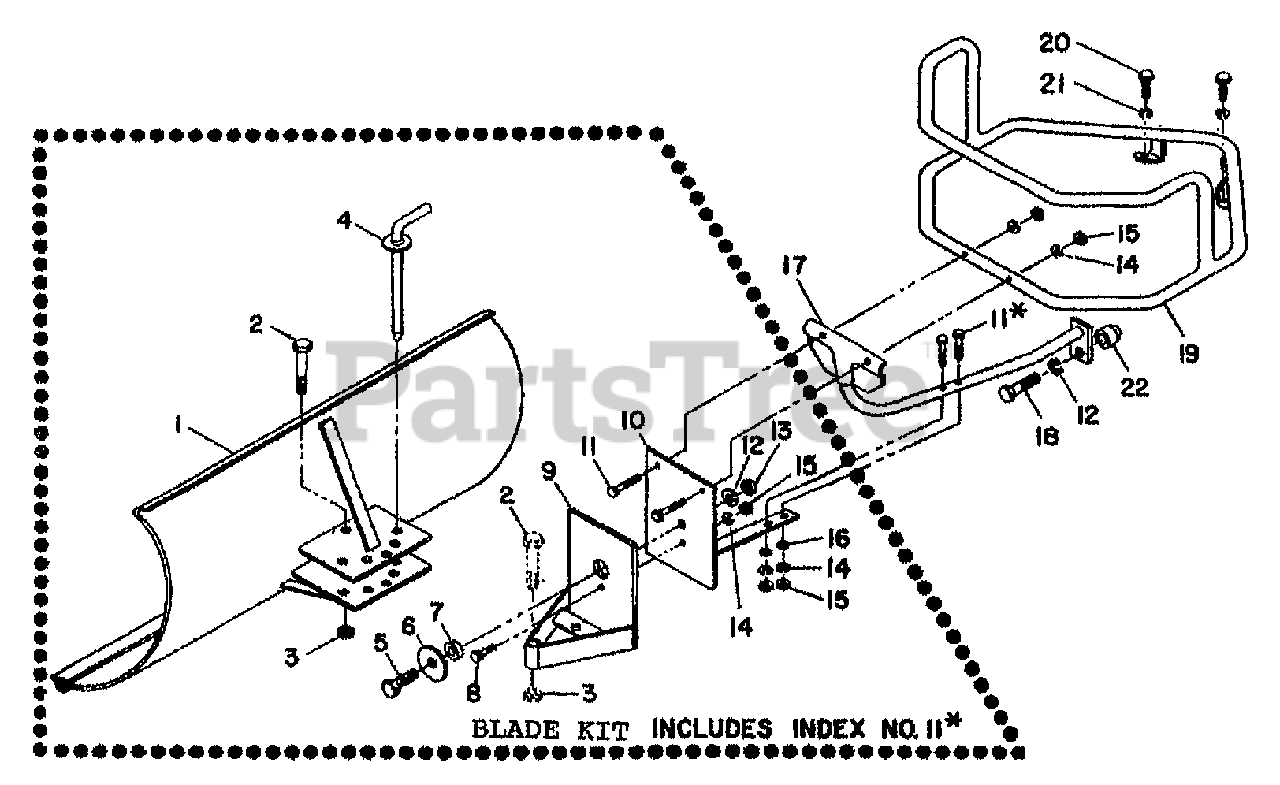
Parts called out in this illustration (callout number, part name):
1	BLADE-DOZER PAINTED
2	SCR-HH 1/2-13X3.0 G5
3	NUT-H/LK 1/2-13
4	INDEX PIN-DOZER PNT
5	SCR-HH 1/2-13X1.5 G5 ZP
6	WASHER-PLAIN 1/2 ZP
7	BUSHING-.75X.51X.41
8	SCR-HH 5/16-18X1.25 G5ZP
9	BRKT-SWIVEL PNT
10	BRKT-MOUNTING T/B PNT
11	SCR-HH 5/16-18X1.75
12	WASHER-LK .5
13	NUT-HEX JAM 1/2-13
14	WASHER-LK .312 ZP
15	NUT-HEX 5/16-18 ZP
16	WASHER-FLAT 5/16 SAE
17	BRACE-BOTTOM
18	SCR-HH 1/2-13X1.5 G5 ZP
19	GUARD-BUMPER WRAP-AROUND
20	SCR-HH 3/8-16X1.0 G5 ZP
21	WASHER-LK .375 @ DEPL
22	SPACER-1.0X.546X.5
